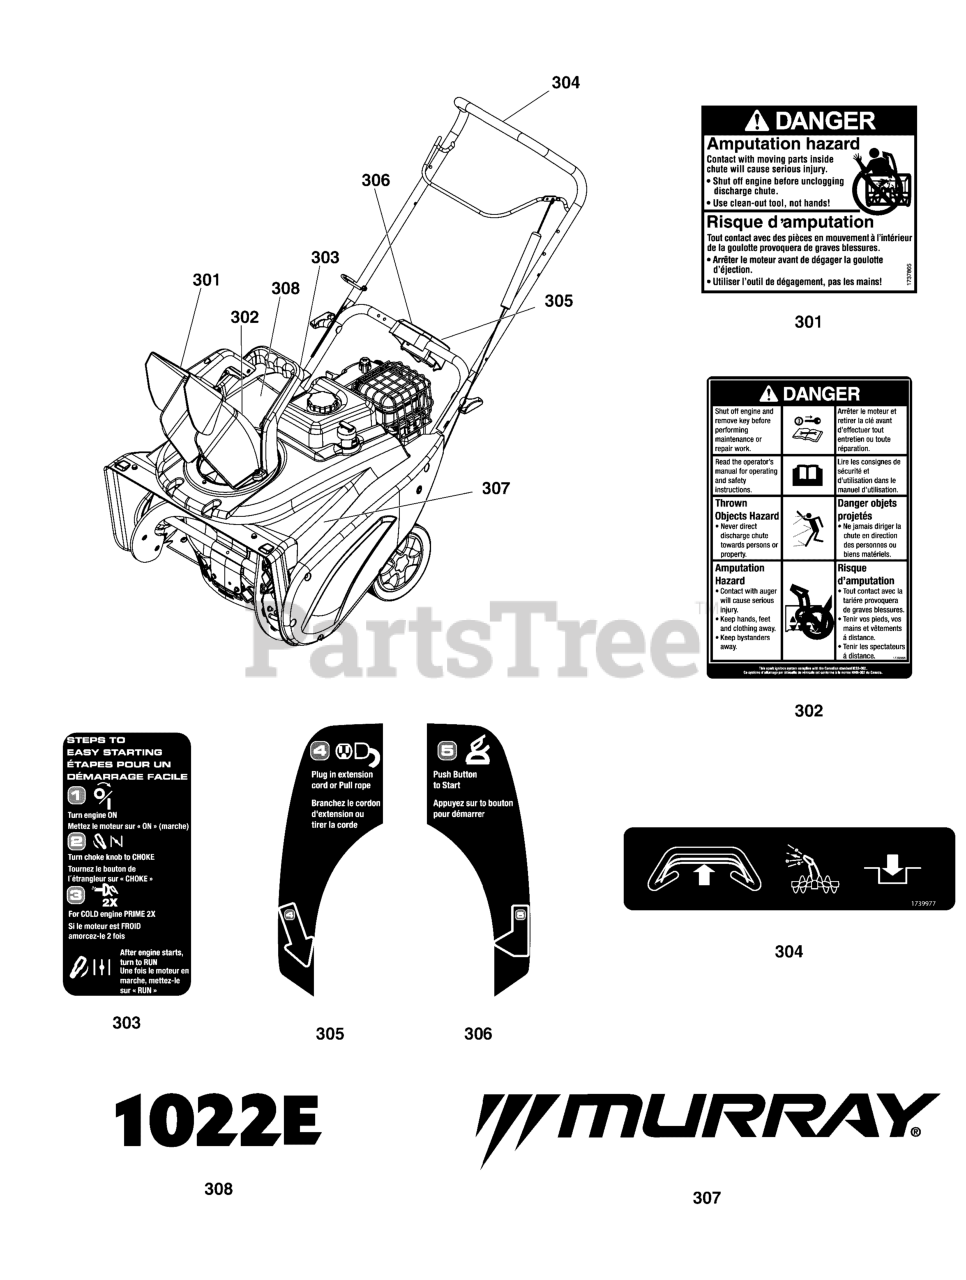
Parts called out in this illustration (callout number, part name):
301	DECAL, Danger Chute Warning, FR/ENG
302	DECAL, Chute, FR-EN
303	DECAL, 1-2-3 Start, FR-EN
304	DECAL, Bail Engagement
305	DECAL, 4, START, FR-EN
306	DECAL, 5, START, FR-EN
307	DECAL, Murray Logo 8.5
308	DECAL, Murray Model 1022E
